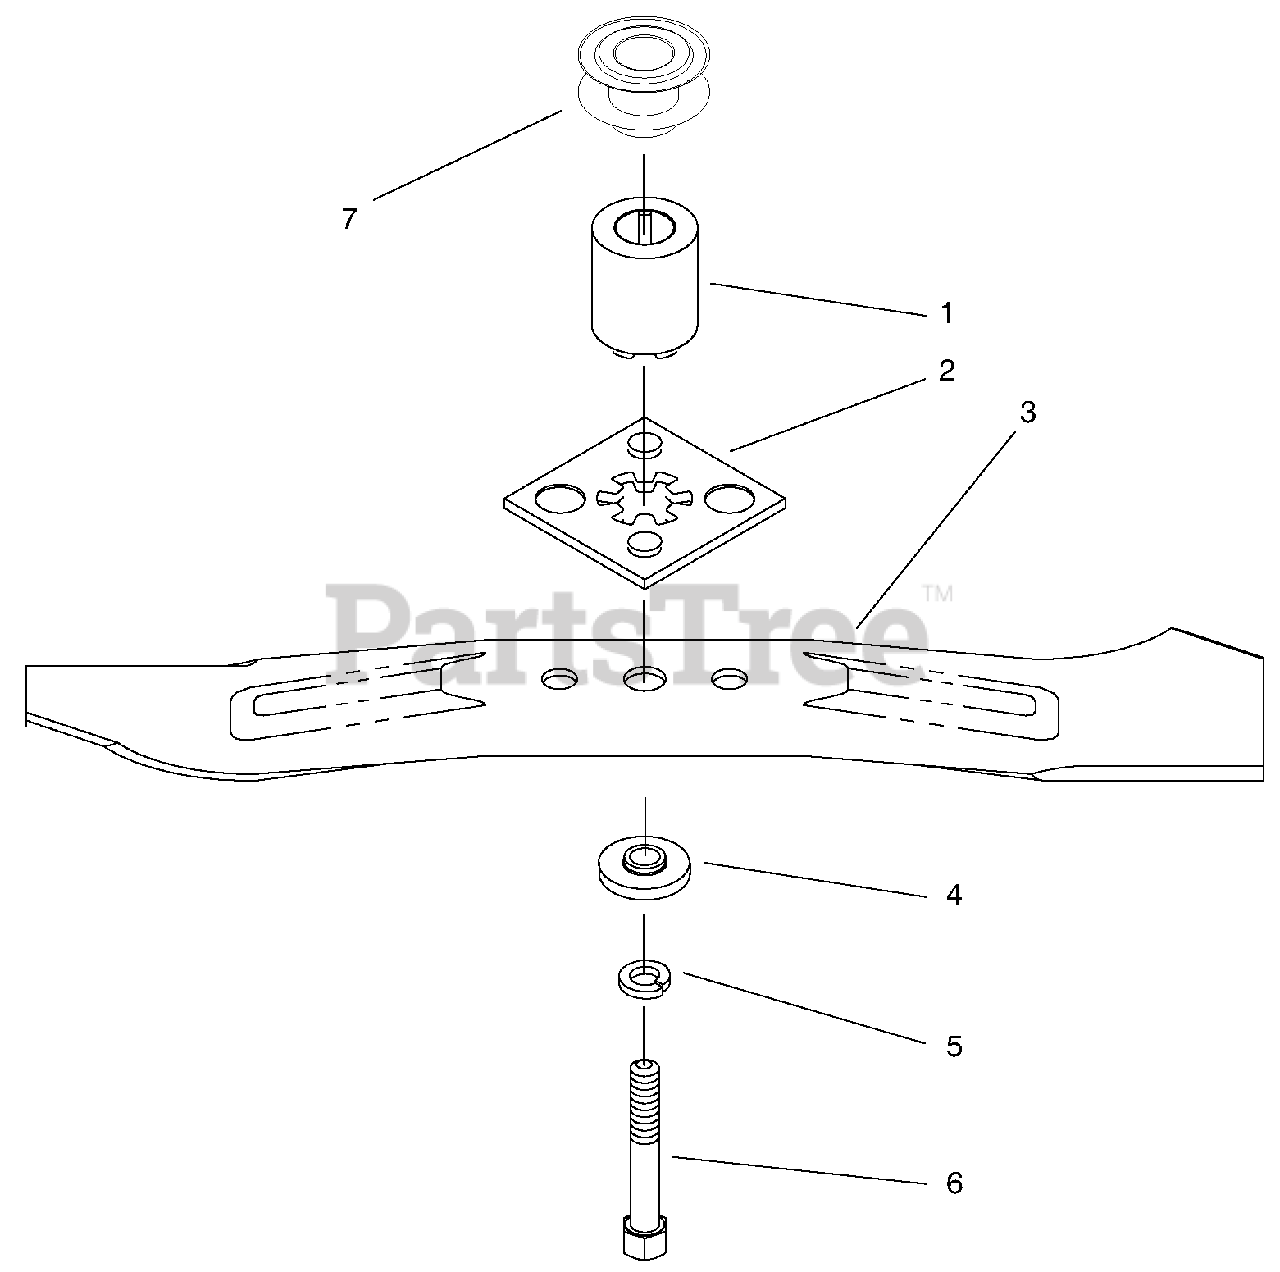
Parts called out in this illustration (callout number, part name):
1	Hub-Blade Driver
2	Plate-Blade Driver
3	Blade-48cm
4	Spacer-Blade
5	Washer-Lock
6	Bolt-Blade
7	Pulley-Driver
